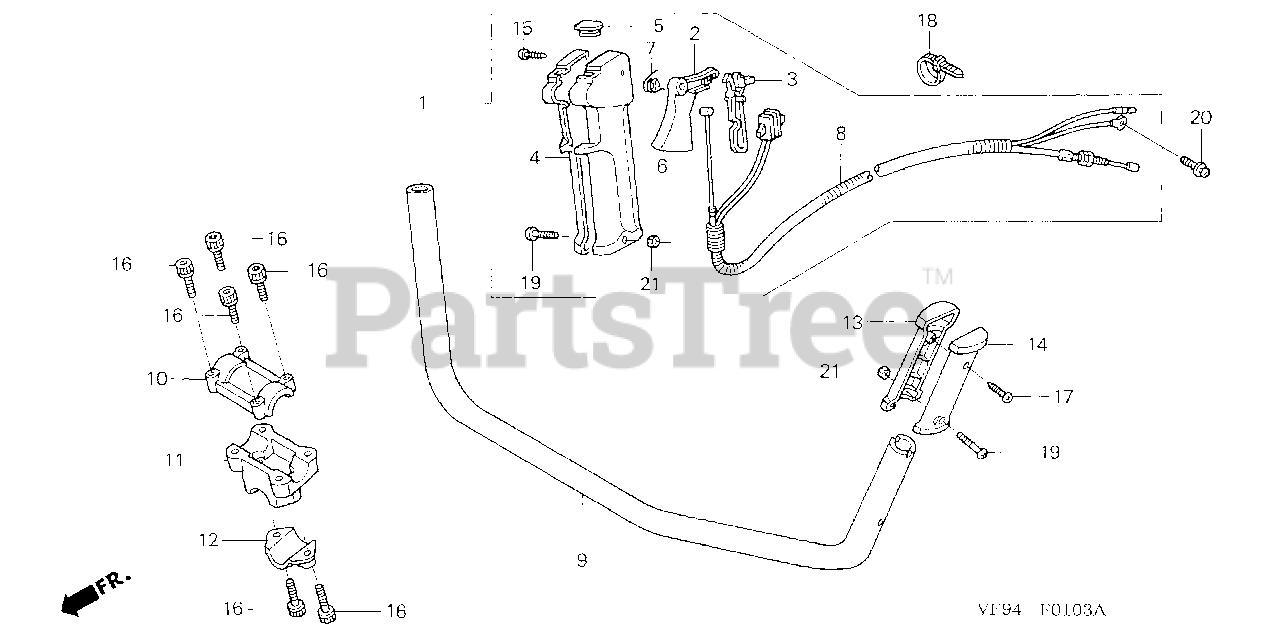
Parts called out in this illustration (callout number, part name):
1	LEVER ASSY., THROTTLE (U)
2	LEVER, THROTTLE
3	LEVER, THROTTLE LOCK
4	GRIP, R. THROTTLE LEVER
5	CAP, THROTTLE LEVER
6	GRIP, L. THROTTLE LEVER
7	SPRING, THROTTLE LEVER
8	WIRE HARNESS ASSY.
9	PIPE, HANDLE
10	HOLDER A, HANDLE
11	HOLDER B, HANDLE
12	HOLDER C, HANDLE
13	GRIP A, HANDLE
14	GRIP B, HANDLE
15	SCREW, TAPPING (4X20)
16	BOLT, SOCKET (6X30)
17	SCREW, TAPPING (5X16) (PO)
18	BAND, WIRE HARNESS
19	SCREW, PAN (5X30)
20	SCREW-WASHER (5X12)
21	NUT, HEX. (5MM)
